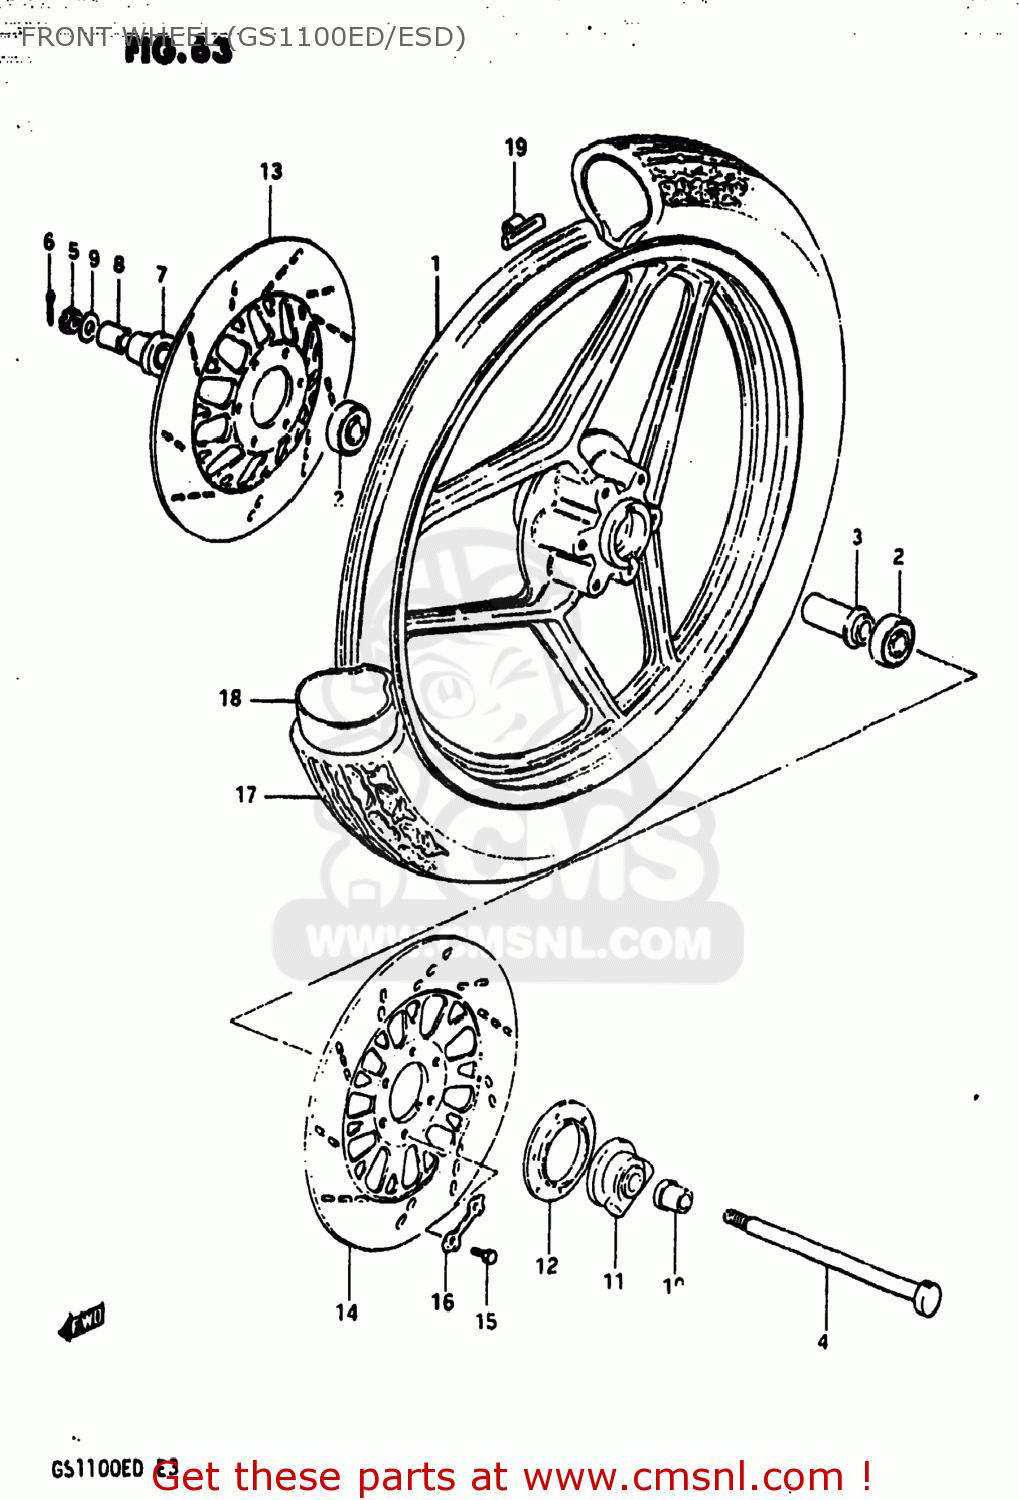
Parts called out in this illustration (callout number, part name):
1	CASTING WHEEL,FRONT 1.85
2	BEARING
3	SPACER,FR HUB BEARING
4	AXLE,FR
5	NUT 12MM
6	COTTER PIN
7	SPACER,FR AXLE,R
8	SPACER,FR AXLE,R
9	WASHER
10	SPACER,FR AXLE,L
11	BOX ASSEMBLY,SPEEDOMETER GEAR
12	DUST SEAL,SPEEDOMETER GEAR BOX
13	DISC,FR BRAKE,R
14	DISC,FR BRAKE,L
15	BOLT(8X25)
16	WASHER
17	TIRE,FRONT
18	TUBE,INNER
19	BALANCER,WHEEL
